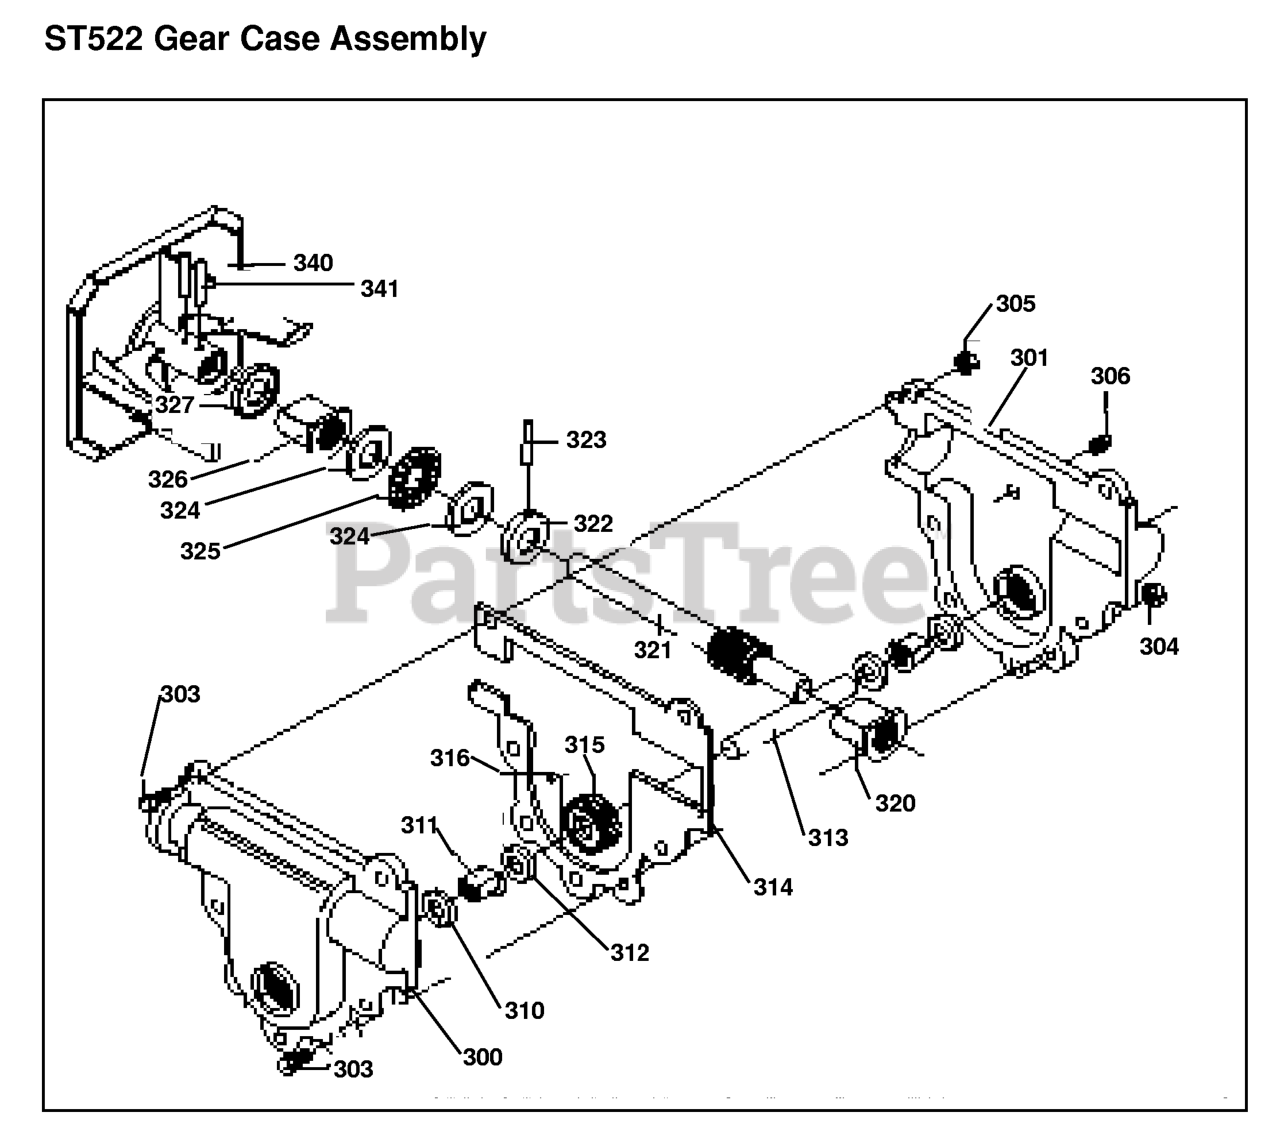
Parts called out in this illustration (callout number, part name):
300	GEAR CASE, RH
301	GEAR CASE, LH
303	SCREW, 1/4-20 X .75
304	NUT 1/4-20
305	NUT, 1/4-20 HEX KEPS
306	SCREW, 3/8-16X.50
310	SEAL, OIL, .75 X 1.19 X .25
311	BEARING, FLANGE
312	FLATWASHER
313	Shaft, Auger Output
314	GASKET, GEAR CASE
315	GEAR, WORM
316	KEY, WOODRUFF
320	BRNG, FL .502IDX .752OD
321	SHAFT, WORM IMP INPUT
322	COLLAR, THRUST
323	PIN, SPRING
324	FLATWASHER
325	ROLLER BEARING
326	BEARING, FLANGE
327	SEAL, OIL, .75 X 1.19 X .25
340	IMPELLER, ASSY
341	PIN, SPRING
